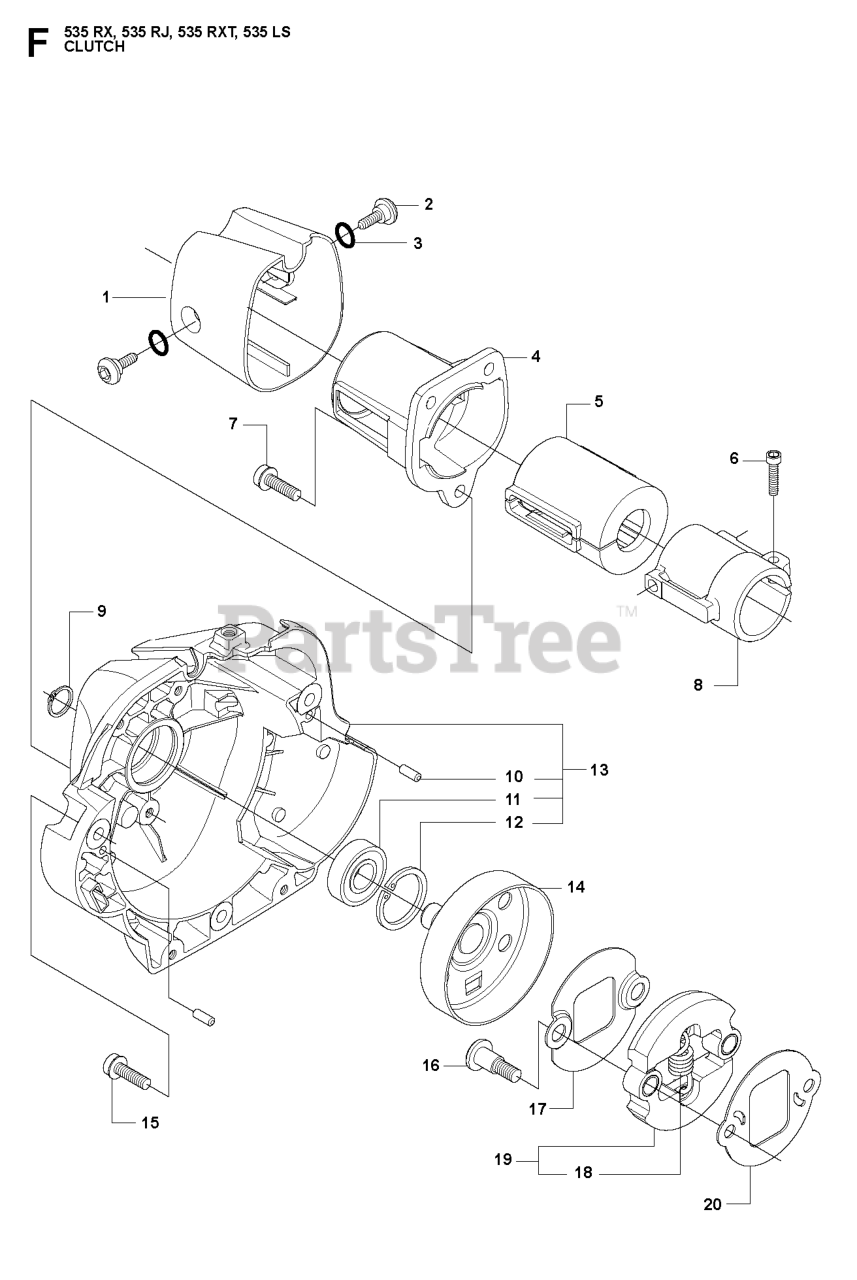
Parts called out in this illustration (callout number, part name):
1	COVER
2	SCREW MT5X11
3	O-RING 8X1.6
4	HOLDER, TUBE
5	VIBRATION ABSORBER
6	SCREW MC6S 5X25
8	SLEEVE, COVER
9	SEEGER CLIP
11	BALL BEARING
12	RETAINING RING SGH 28
13	CLUTCH COVER
14	CLUTCH DRUM
16	SCREW CLUTCH
19	CLUTCH CPL
20	WASHER
